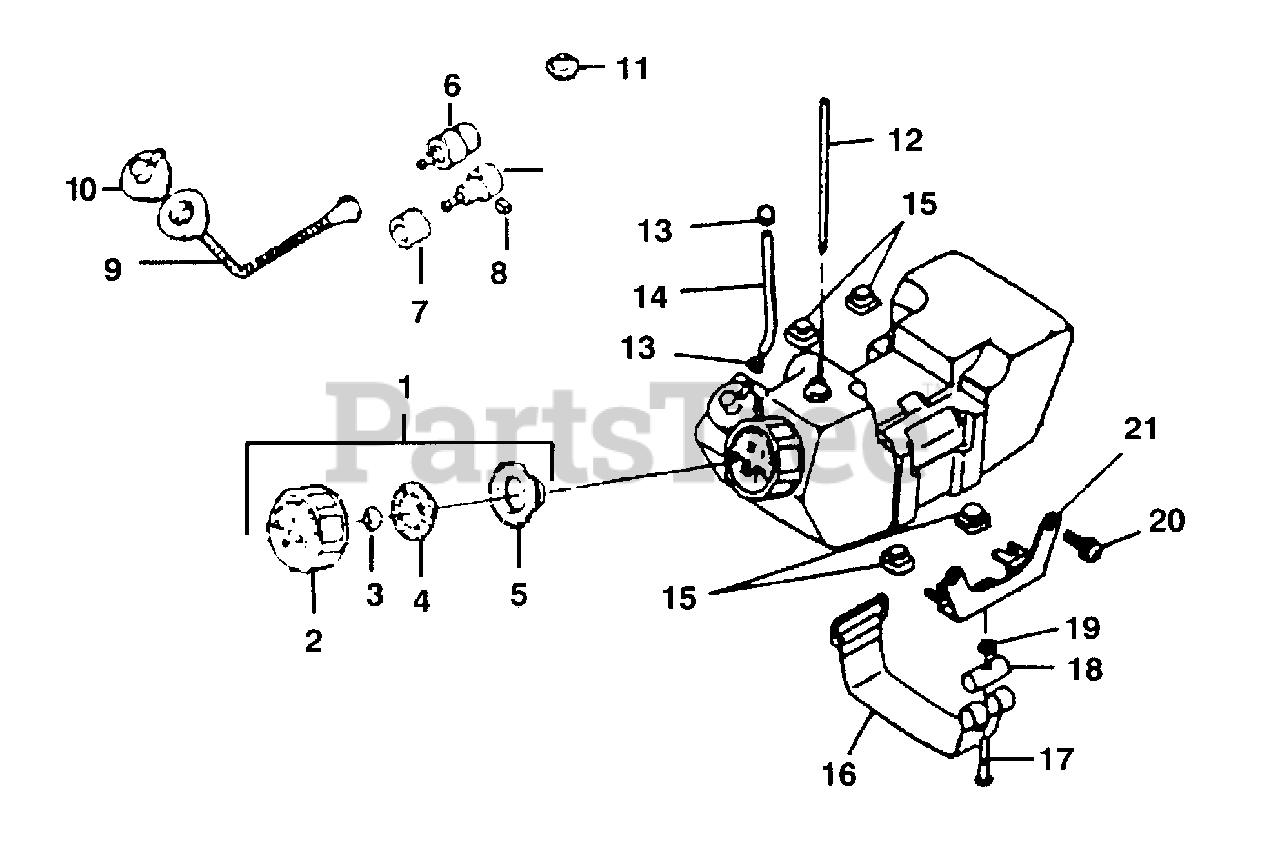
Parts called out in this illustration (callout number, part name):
3	BREATHER VALVE
6	FUEL FILTER ASSY
9	HOSE, SUCTION
12	FUEL TUBE
14	FUEL TUBE
16	TANK BAND
17	SCREW
20	SCREW & WASHER
21	HANGER, BRACKET
